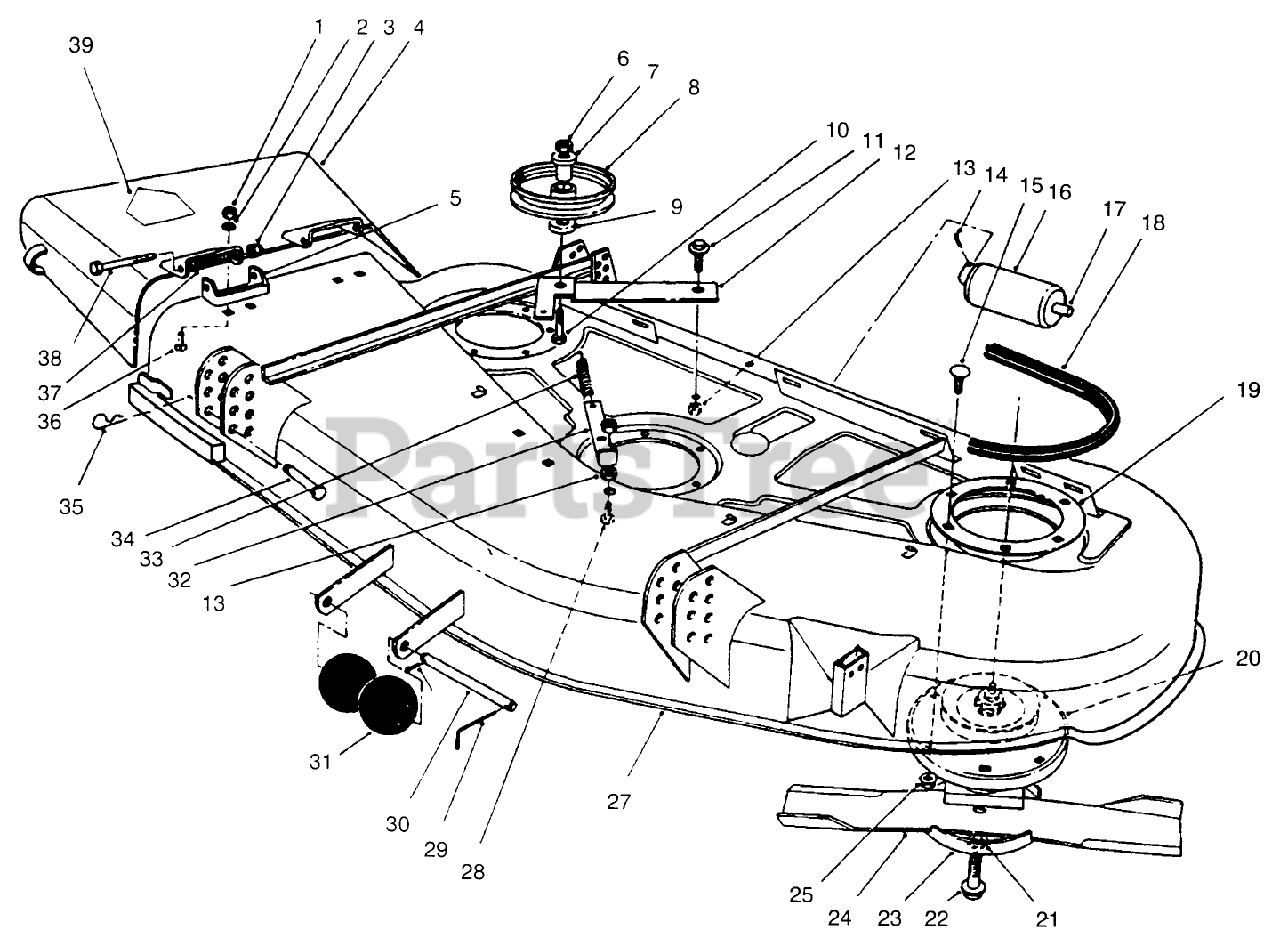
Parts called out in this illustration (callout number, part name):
1	NUT-HEX
2	WASHER-LOCK
3	NUT-HEX
4	Deflector
5	Bracket-Pivot
6	NUT-HEX
7	BUSHING-PULLEY
8	PULLEY-IDLER
9	WASHER-FLAT
10	SCREW-HH
11	SCREW-SHOULDER
12	Lever-Deck
13	NUT-LOCK, NI
14	PIN-COTTER
15	SCREW-CARR
16	ROLLER-DECK
17	SHAFT-ROLLER, REAR
18	V-BELT, DECK
19	SUPPORT-DECK, RING
20	SPINDLE HSG ASM
21	WASHER-LOCK
22	SCREW-BLADE
23	CUP-SCALP, ANTI
24	Blade
25	NUT-HF
27	Deck
28	SCREW-CARR
29	PIN-SPECIAL
30	SHAFT-ROLLER
31	ROLLER
32	Anchor-Spring
33	SPRING-EXTENSION, DECK
34	PIN-CLEVIS
35	PIN-HAIR
36	SCREW-CARR
37	SPRING
38	SCREW-HH
39	Spacer
